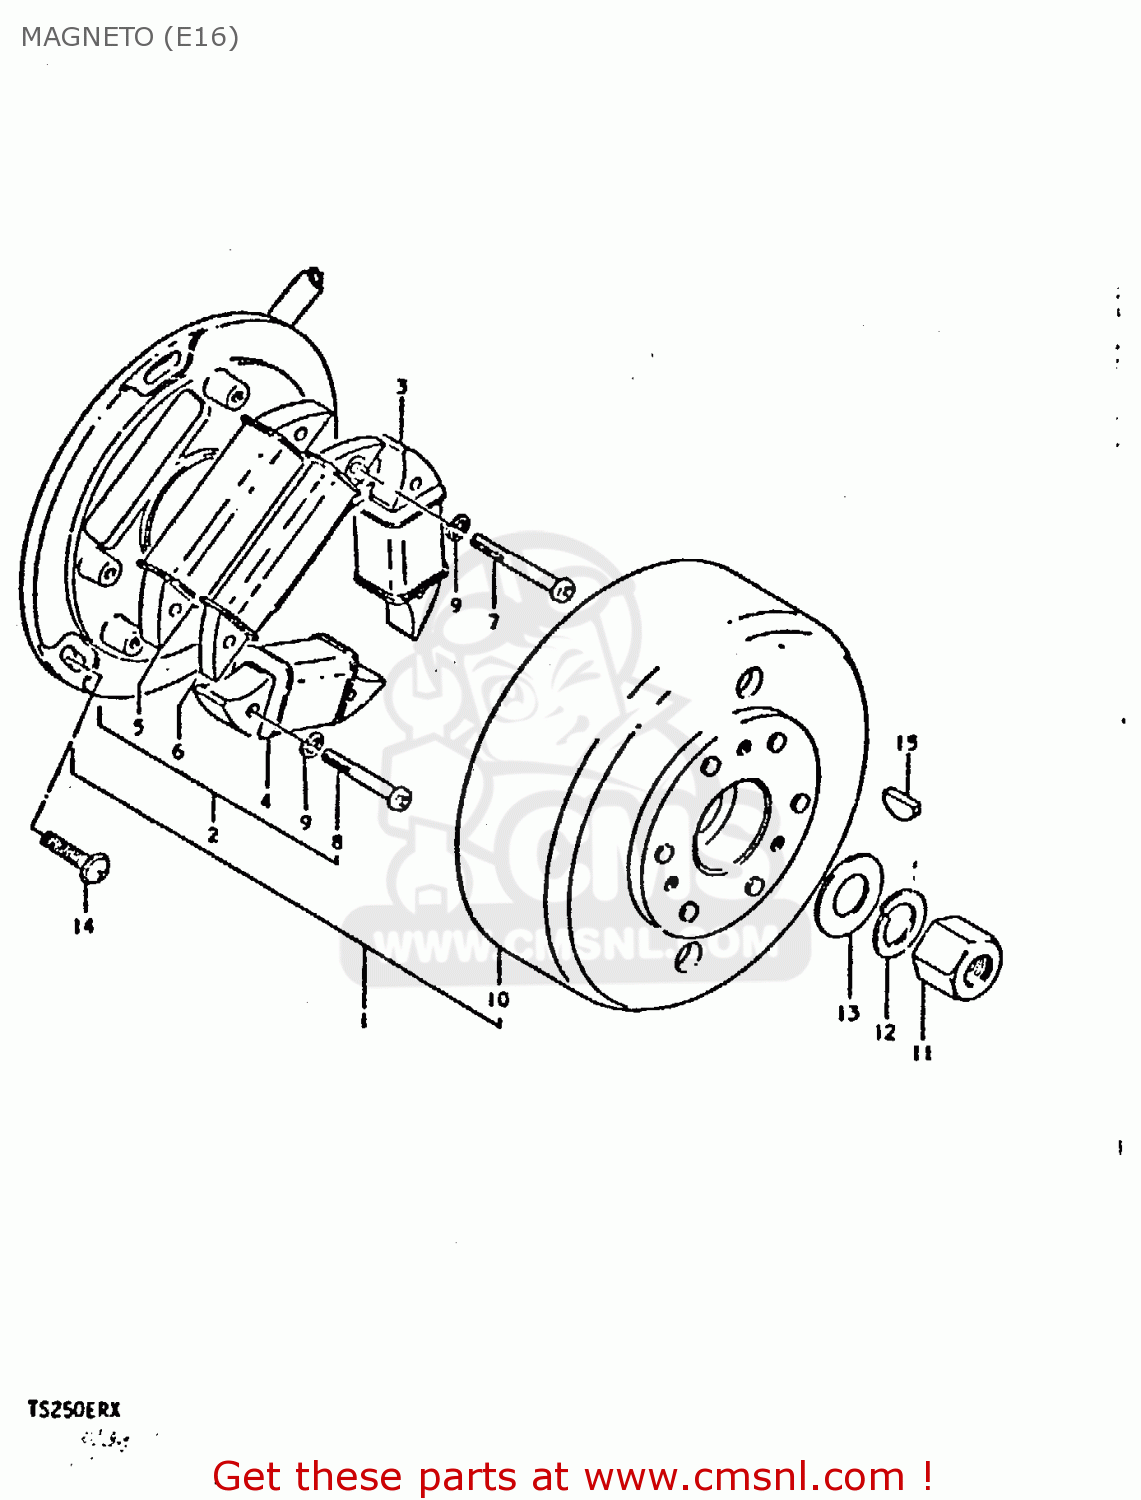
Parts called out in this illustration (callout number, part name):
1	MAGNETO ASSY
2	STATOR ASSY
3	COIL, LIGHTING
4	COIL,LIGHTING
5	COIL,PRIMARY
6	COIL,PULSER
7	SCREW
8	SCREW 5X20
9	LOCK WASHER
10	ROTOR,FLYWHEEL
11	NUT
12	LOCK WASHER
13	WASHER(14X27X3)
14	SCREW(5X14)
15	KEY 4MM
